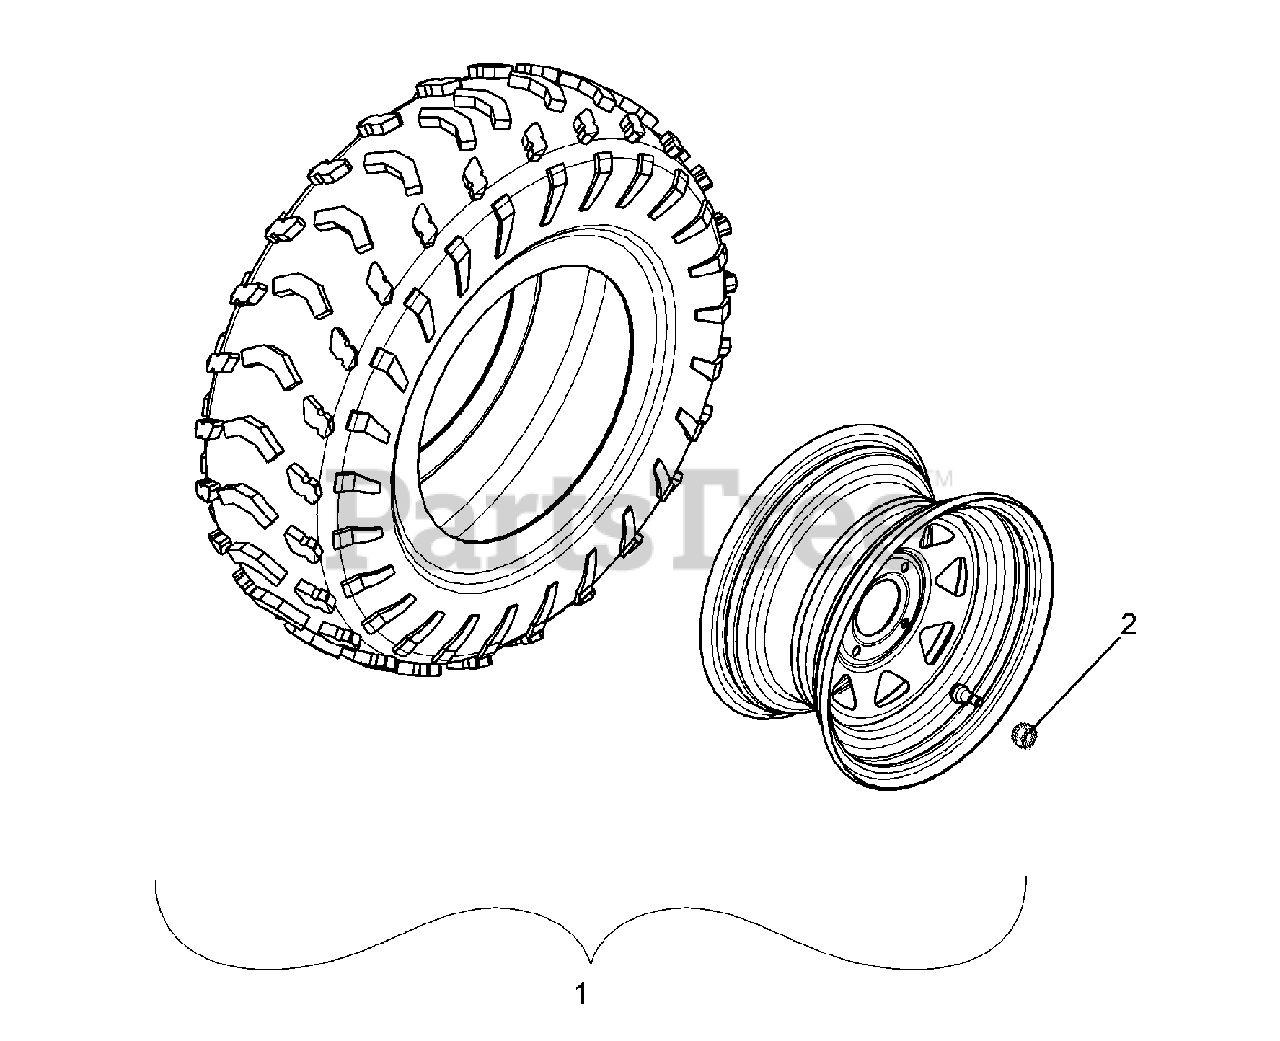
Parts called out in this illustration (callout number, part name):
1	AT TIRE/RIM, RIGHT FRONT BLK
1	AT TIRE/RIM LEFT FRONT BLK
2	NUT, 1/2-20 LUG, GRADE 5
